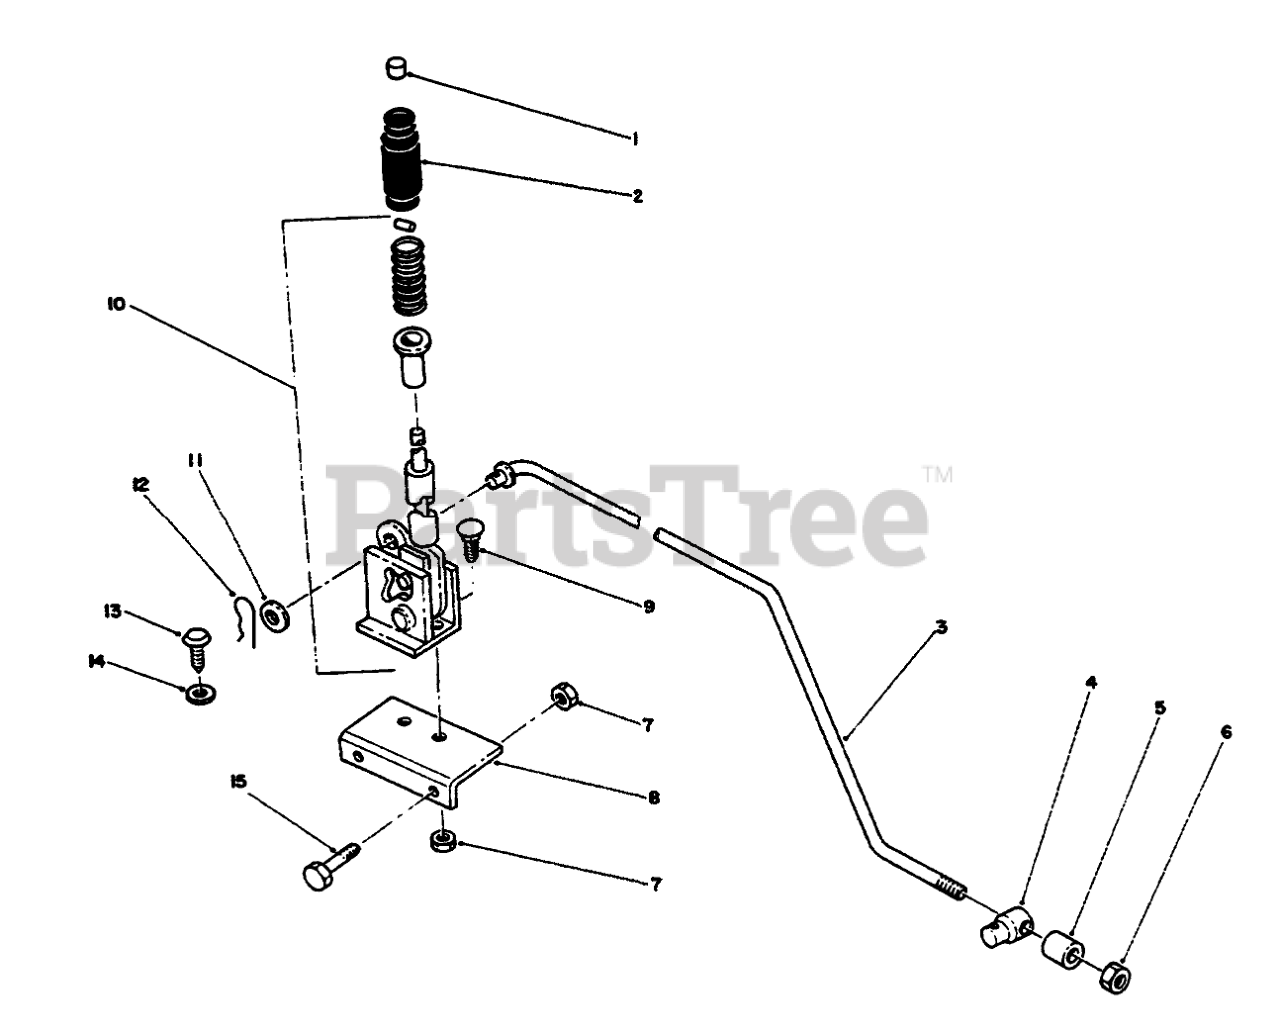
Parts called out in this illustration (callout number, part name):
1	CAP-ROD, PLUNGER
2	HANDGRIP
3	LIFT ROD ASM
4	TRUNION
5	Spacer
6	NUT-LOCK, NI
7	NUT-LOCK, NI
8	Bracket-Support
9	BOLT-CARR
10	ASS'Y-LIFT HANDLE R
11	WASHER-FLAT
12	Hairpin
13	FOOTPAD FASTENER
14	WASHER-FLAT
15	SCREW-HH
